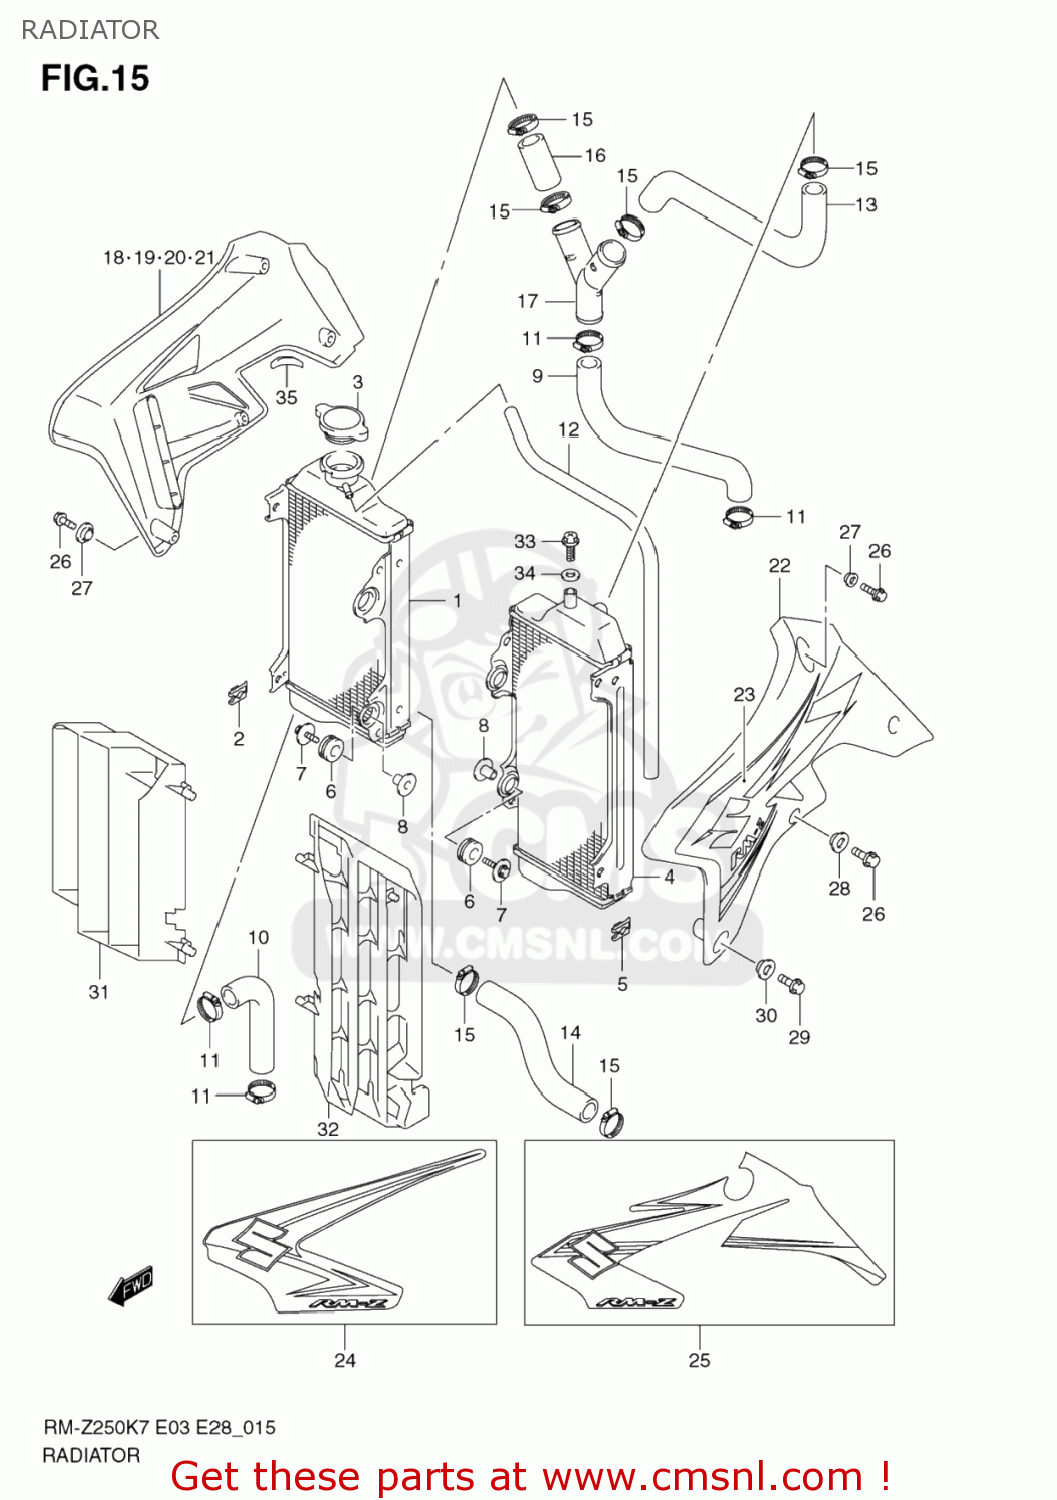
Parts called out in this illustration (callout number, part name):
1	RADIATOR,WATER,R
2	NUT
3	CAP COMP,RADIATOR
4	RADIATOR,WATER,L
5	NUT
6	CUSHION,RADIATOR LWR
7	BOLT(6X25)
8	SPACER(6.5X10.5X14.1)
9	HOSE,RADIATOR INLET
10	HOSE,RADIATOR OUTLET
11	CLAMP
12	HOSE(5X8X1000)
13	HOSE,RADIATOR JOINT UPR NO.1
14	HOSE,RADIATOR JOINT LWR
15	CLAMP
16	HOSE,RADIATOR JOINT UPR NO.2
17	JOINT,RADIATOR HOSE
18	COVER,RADIATOR,R(YELLOW)
19	TAPE,RADIATOR COVER,R
20	TAPE,RADIATOR COVER,R
21	TAPE,RADIATOR COVER,R
22	COVER,RADIATOR,L(YELLOW)
23	TAPE,RADIATOR COVER,L
24	TAPE,RADIATOR COVER,L
25	TAPE,RADIATOR COVER,L
26	BOLT(6X12)
27	WASHER
28	WASHER
29	BOLT(6X16)
30	SPACER(6.3X10X6)
31	LOUVER,RADIATOR,R
32	LOUVER,RADIATOR,L
33	UNION BOLT,AIR VENT
34	GASKET(6.4X11.5X0.8) (NAS)
35	CUSHION,RADIATOR COVER
